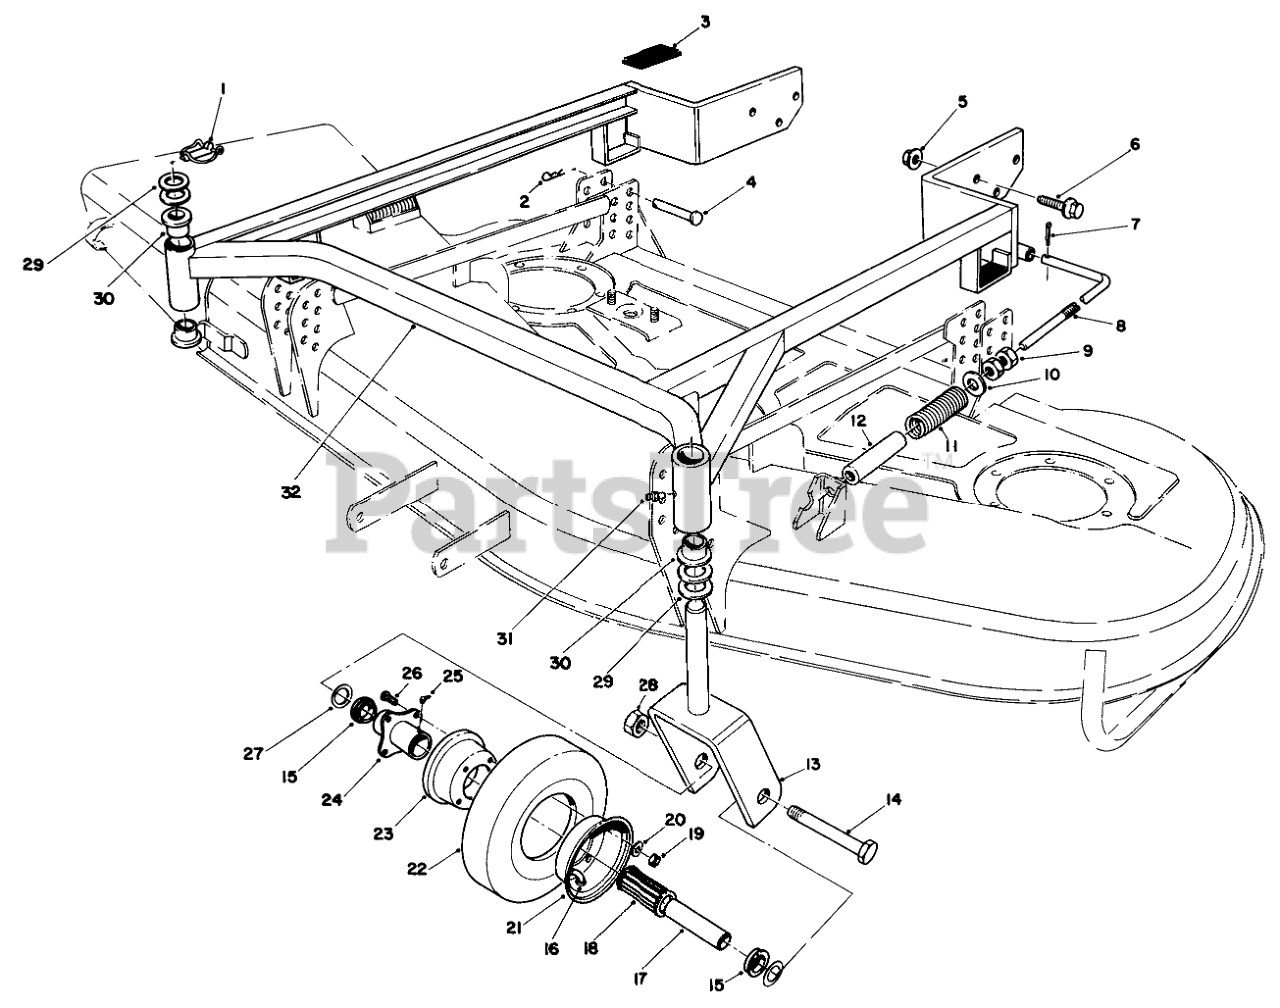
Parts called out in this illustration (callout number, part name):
1	PIN-LYNCH
2	PIN-HAIR
3	Cushion-Rubber
4	PIN-CLEVIS
5	NUT-LOCK, FLANGE
6	SCREW-HHF
7	PIN-COTTER
8	ADJUSTING SHAFT
9	NUT-JAM
10	WASHER
11	SPRING-COMPRESSION
12	SLEEVE-TUBE, 36 INCH
13	FORK-Castor
14	SCREW-HH
15	RETAINER
17	Bushing-Spanner
18	BEARING-ROLLER
19	NUT-HEX
20	WASHER-LOCK
21	WHEEL HALF-MALE
22	TIRE-8 Inch (4-PLY)
23	WHEEL HALF-FEMALE
24	HUB-CENTERED
25	FITTING-GREASE
26	WHEEL BOLT
27	SPACER-WHEEL
28	NUT-LOCK
29	WASHER-THRUST
30	Bushing
31	FITTING-GREASE
32	Frame-Carrier (Incl. Ref. #30)
